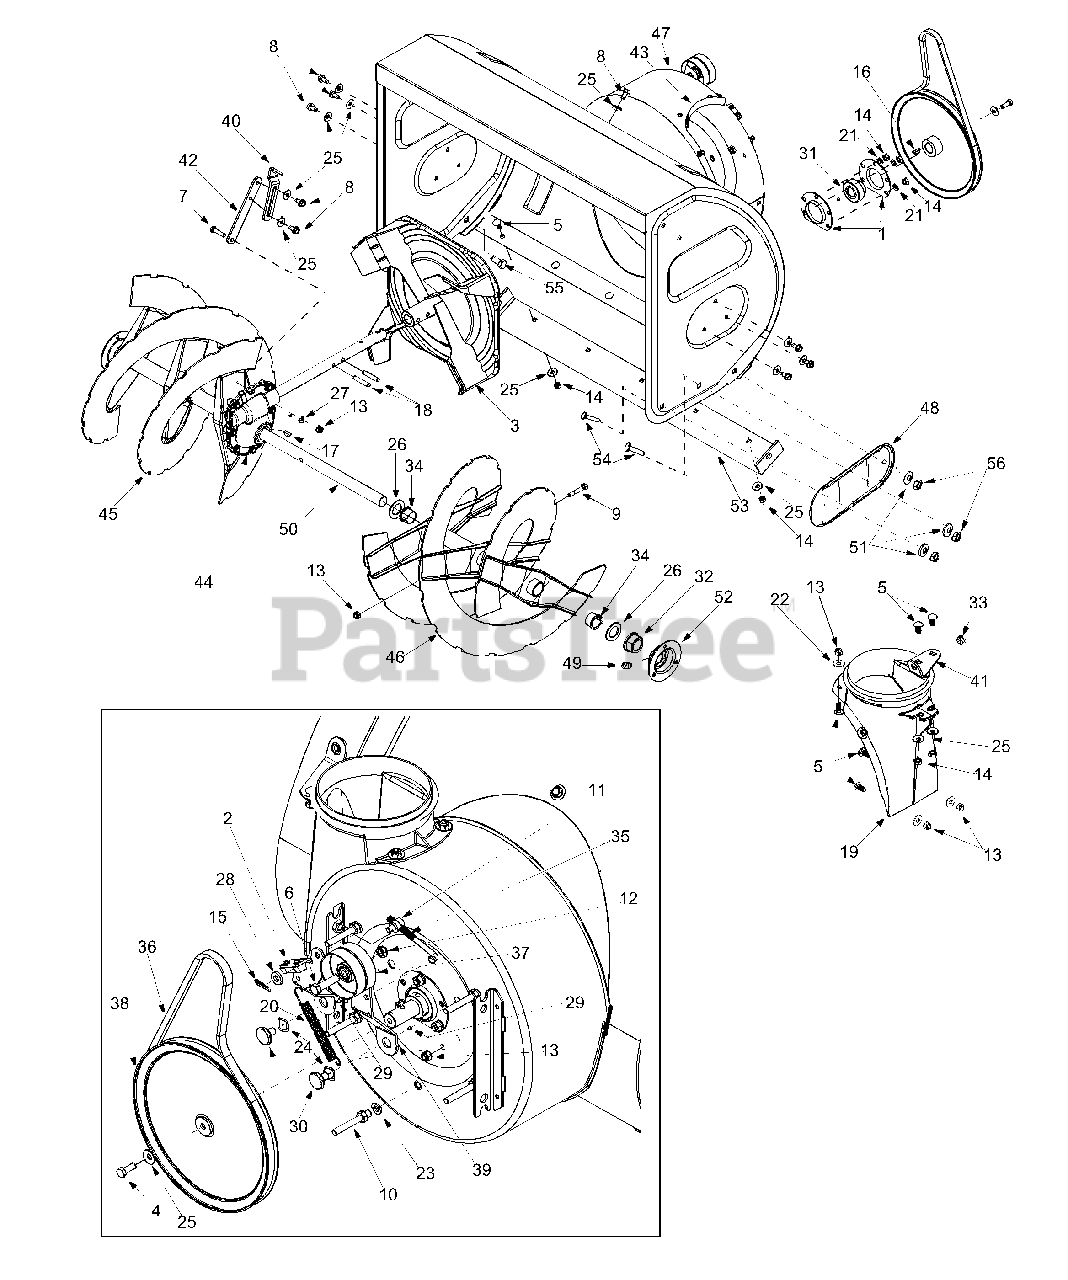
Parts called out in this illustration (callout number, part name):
1	Bearing Housing
2	Bracket Assembly: Auger Break
3	Impeller Assembly: 16"
4	Hex Lock Bolt 5/16-18 x .875"
5	Carriage Bolt 5/16-18 x .750"
6	Hex Screw, Special 3/8-24 x 1.5"
7	Hex Screw 5/16-18 x 1.25"
8	Self-Tapp. Screw 5/16-18 x .625"
9	Shear Bolt 5/16-18 x 1.75"
10	Stud
11	Ferrule
12	Jam Nut 3/8-24
13	Hex Lock Nut 5/16-18
14	Hex Nut 5/16-18
15	Hairpin Clip
16	Key
17	Key
18	Spiral Pin
19	Chute Adapter
20	Extension Spring
21	Lock Washer
22	5/16 Washer
23	Lock Washer
24	Wave Washer
25	Beleville Washer
26	Flat Washer
27	Spring Washer
28	Flat Washer
30	Shoulder Screw
31	Self-Aligning Bearing
32	Flange Bearing w/ Flats
33	Plastic Bushing
34	Flange Bushing
35	Idler Rod: Auger
36	V-Belt
37	Flat Idler
38	Pulley
39	Idler Bracket: Auger
40	Support Bracket
41	Chute Crank Bracket
42	Support Plate
43	Chute Bracket
44	Gear Assembly
45	Spiral Assembly RH
46	Spiral Assembly LH
49	Lube Fitting
50	Spiral Axle
51	Bell Washer
52	Bearing Housing
53	Shave Plate
54	Carriage Screw
55	Carriage Bolt
56	Hex Nut 3/8-16
